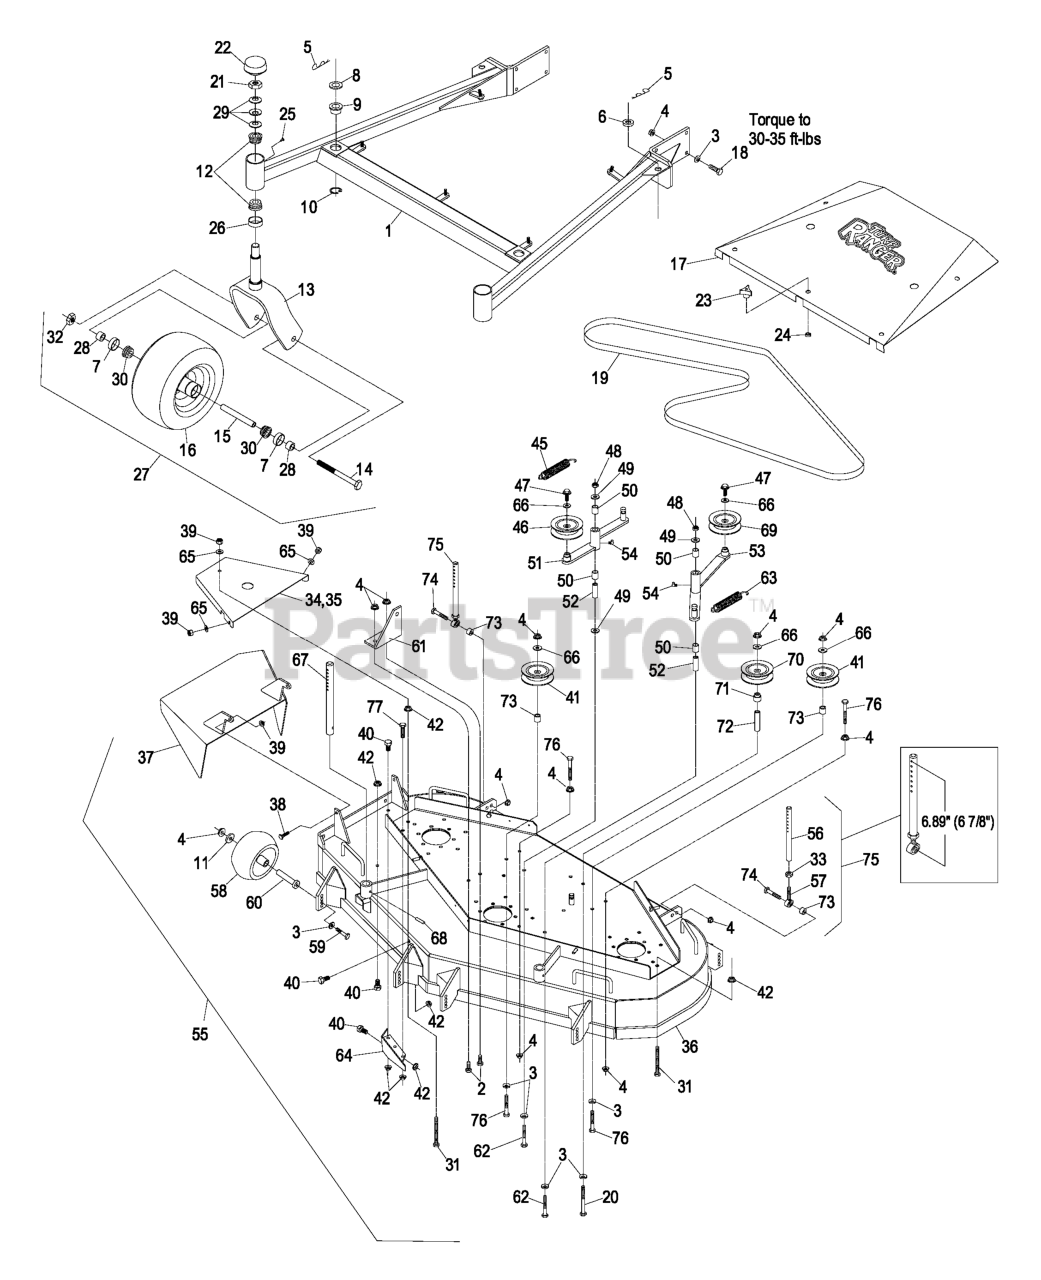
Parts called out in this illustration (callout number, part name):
1	ASM,FMD604 DK SUPPORT, SE
2	SCREW-HH
3	WASHER-BELLEVILLE
4	NUT-HHF, WHIZ
5	PIN,HAIR COTTER
7	SEAL-CASTER
8	SPACER-DECK SUPPORT
9	BUSHING-DECK
10	RING-RETAINING
12	Cone-Bearing Tapered Roller
13	WLD, CASTER FORK
14	SCREW-HH
15	SPACER,FRONT CASTER
17	KIT,SHIELD TR604 W/ DECAL
18	SCREW-HH
19	BELT,MULE DRIVE
20	SCREW-HH
21	NUT-LOCK, NI
22	CAP-GREASE
23	KNOB-3 PRONG
26	SEAL-GREASE
28	SPACER-BEARING
29	WASHER-BELLVILLE
30	BEARING-CONE, TAPERED ROLLER
31	BOLT,TAP HH
32	NUT-HEX
33	NUT-HEX
34	SHIELD,BELT RH
35	SHIELD,BELT LH
37	WLD,CHUTE FMD604
38	SCREW-HH
39	NUT-LOCK, NI
40	SCREW-HH
41	IDLER,PULLEY
43	SPACER,TUBE
44	SHEAVE,BLADE DRIVE
45	SPRING-EXTENSION
46	IDLER,PULLEY
47	SCREW-HHF
48	NUT-LOCK, NI
49	WASHER-FLAT
50	SLEEVE-BEARING
51	ASM,IDLER ARM
52	BUSHING-PIVOT, IDLER
53	ASM,IDLER ARM
54	FITTING-GREASE, 90 DEG
55	Complete Deck Assy
56	LINK,SUPPORT
57	BALLJOINT
58	ROLLER-SCALP, ANTI
59	SCREW-HH
60	BUSHING-ROLLER
61	BRACKET,SPRING ANCHOR
62	SCREW-HH
63	SPRING-EXTENSION
64	WLD,BAFFLE DISCHARGE
65	WASHER-FLAT
66	WASHER-FLAT
67	ROD,DECK SUPPORT
69	PULLEY-IDLER
70	PULLEY-IDLER
71	BUSHING,IDLER
72	SPACER-ANCHOR, CLUTCH
74	SCREW-HH
76	BOLT-CARR
77	SCREW-HH
